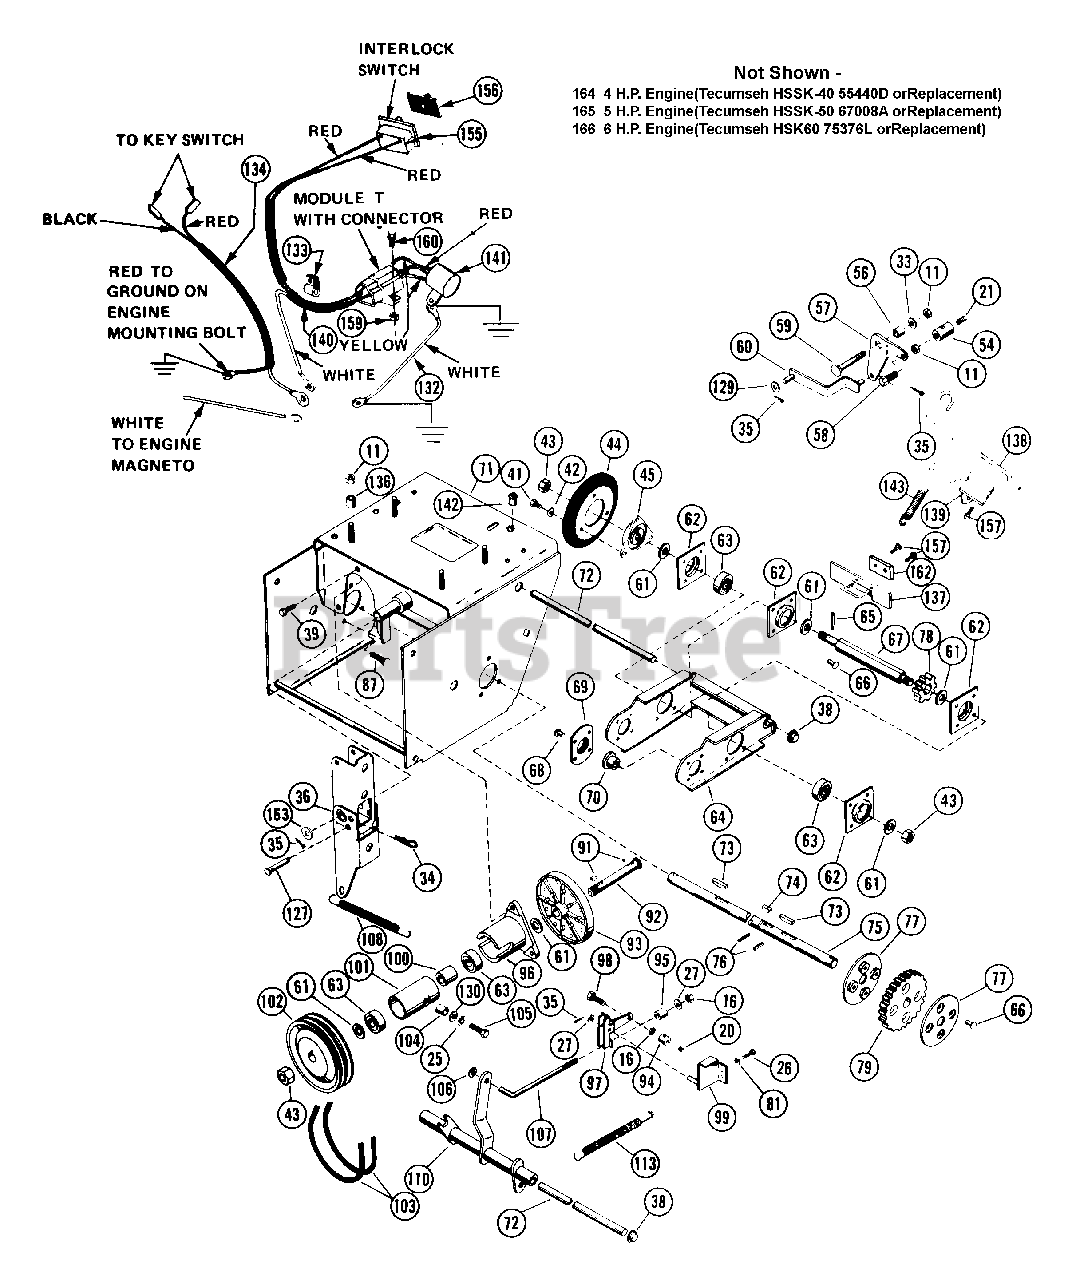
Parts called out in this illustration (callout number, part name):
1	BLT-HEX .31-18X1.50 PL GR2
2	WSHR-FL-STL.312X.734X.065PL
4	HANDLE PIVOT
5	SCR-TAP 12-14X1.50 CROVH PL BT
6	SPRINGGRIP FASTENER
7	SHIFT BALL
8	SHIFT HANDLE
9	SHIFT ROD
10	SG-COMP .105X.585X.75
11	NUT-LK .312-18 GR A PL
12	HANDLEBAR ASSEMBLY
13	BLT-HEX .25-20X.75 PL GR2
14	THROTTLE CONTROL
16	NUT-LK-CTR .250-20 PL
17	INNER BELT COVER
18	KEY-WDRF .125X.625X.250 SAE5
19	CAMSHAFT SHEAVE
20	SCR-SET .25-20X.25 SKHCUPNY OH
21	SCR-SET .32-18X.38 SKHCUPNL OH
22	KEY-SQ .188X1.0X.188 SAE 8630
23	BELT FINGER
24	BLT-HEX .31-24X.75 PL GR5
25	WSHR-LK .312X.097 PL HVY
26	BLT-HEX .25-20X.50 PL GR2
27	WSHR-FL-STL .250X.562X.049 PL
28	OUTER BELT COVER
29	BSHG-SLV .500X.625X.937
31	IDLER SHAFT
32	RVT-TBLR .187X1.218 OH ST PL
33	WSHR-FL-STL .38X.875X.083 PL
34	PIN-HAIR INT .08X.18X1.18
35	PIN-COTR .09X.75 PL
36	IDLER ARM ASSEMBLY
37	ENGINE SHEAVE
38	CAP, .50 ROD YWZC
39	BLT-SERHFWH .31-18X.50 PL
40	BLT-RDHDSQSHNK .31-18X.50 YZ
41	BLT-HEX .25-20X.38 PL GR2
42	WSHR-LK-EXT. 250 ID
43	NUT-LK-CTR .50-20 PL
44	FRICTION DISC
45	FRICTION DISC HUB
47	NUT-LK-FLG .250-20 PL
48	WSHR-LK-INT .625X.045 PL
49	CLUTCH HANDLE ASSEMBLY
50	GRIP
51	CLUTCH ROD
52	BLT-HEX .25-20X1.75 PL GR2
53	KEY SWITCH
54	ROD ADAPTER
56	BSHG-SLV .334 X .502 X 1.437
57	SHIFT LEVER
58	BLT-HEX .31-18X.75 PL GR2
59	BLT-RDHDSQNK .31-18X2.0 SHT PL
60	SHIFT LINK
61	WSHR-FL-STL .505X1.000X.062
62	BEARING RETAINER
63	BRG-BALL .500X1.38X.437
64	CARRIER
65	PIN-ROLL .188X1.00
66	RVT-POP .187X.402 DOME ST
67	HEX SHAFT
68	RVT-POP.125 X .294 DOME
69	BEARING RETAINER
70	BSHG-FLG .750X1.000X.625X1.250
71	TRACTOR FRAME
73	KEY-FTHR .188X1.25X.187 SAE
74	KEY-WDRF .25X.750X.313 SAE91
75	AXLE SHAFT
76	PIN-ROLL .125X1.00
77	RETAINER PLATE
79	SPUR GEAR, FELLOWS 35T .750 ID
81	WSHR-LK .250X.077 HVY PL
82	NUT .625-32 ALUM
83	PIN-COTR .12 X 1.25 PL
85	T/WHL ASS,Y
85	TIRE & WHEEL ASSEMBLY
85	TIRE 4.10/3.50-4
85	TUBE
85	T/WHL ASSY 4.80 X 8 AGRI LUG
85	WHL
85	BLT-HEX .38-16X.63 PL GR2
85	WSHR-LK .375X.094 MED PL
85	NUT-HEX .375-16
87	SCR-SLTR-SERNK .25-20X.62 PL
88	WSHR-LK-EXT .500X.040 MED
89	WHEEL HUB
90	SUPPORT, BEARING
91	KEY-WDRF .125X.500X.203 SAE 3
92	SPINDLE
93	DRIVE DISK
94	ROD ADAPTER
96	DRIVE SPINDLE HOUSING
97	DEADMAN LEVER
98	BLT-HEX .25-20X.75 PL GR5
99	DEADMAN BRACKET
100	BEARING SPACER .75 X .5 X.88
101	SPINDLE HOUSING
102	DRIVE SHEAVE
103	V-BELT, SPECIAL-RAW EDGE (SET)
105	BLT-HEX .31-18X1.00 PL GR 2
106	RATCHET PLATE
107	ADJUSTMENT LINK
108	SG-TENS .063X.44X2.81 WLD 18
109	ROD HANGER EYEBOLT
111	SPINDLE CUP
112	HUB CAP
113	SG-TENS .125X.437X5.5 WLD 20
115	CLUTCH LEVER ROD
116	WSHR-FL-STL .382X.812X.023 PL
117	SUPPORT BRACKET
118	UNIVERSAL JOINT ASSEMBLY
119	SCR-MCH .31-24X.75 CRFL
120	WSHR-LK-EXT .313X.025
122	PIN-COTR .12X1.0 PL
123	CLUTCH ROD
124	BLT-HEX .31-18X.75 PL GR2
124	BLT-HEX .75-16X2.50 PL GR5
127	CLEVIS PIN
129	WSHR-FL-STL .250X.562X.125 PL
130	WSHR-FL-STL.344X.688X.065PL
131	WSHR-FL-STL.406X.812X.065PL
132	WIRE GROUND
134	SHORTING WIRE
135	CLIP WIRING
136	ENG BOLT SPCR
137	BRACKET SWITCH
138	ACTUATOR SWITCH
139	RETAINER ROD
140	WIRING HARNESS
141	MODULE T SERVICE ASSEMBLY
142	SNAP BUSHING-.437
143	SG-TENS .026X.38X3.75 WLD 1.58
144	SG-TENS .063X.44X1.56
145	ROD UPPER INTERLOCK
146	HANDLE INTERLOCK
147	PIN PIVOT
148	CONNECTING LINK
149	LOWER ROD INTERLOCK
150	PUSH NUT, .25
153	PIN-COTR .06X.50
154	NUT-HEX .250-20 PL
156	SWITCH BOOT
157	SCR-TAP 10-24X.375 HWH PL TR
158	KEYS
159	NUT-LK TOP 10-24 PL
160	BLT-HEX 10-24X.38 PL GR2
161	CONNECTOR
162	STRAP - SWITCH BRACKET
163	WSHR-FL-STL.406X.812X.065PL
164	4 H.P. Engine(Tecumseh HSSK-40 5544OD orReplacement)
165	5 H.P. Engine(Tecumseh HSSK-50 67008A orReplacement)
166	6 H.P. Engine(Tecumseh HSK60 75376L orReplacement)
